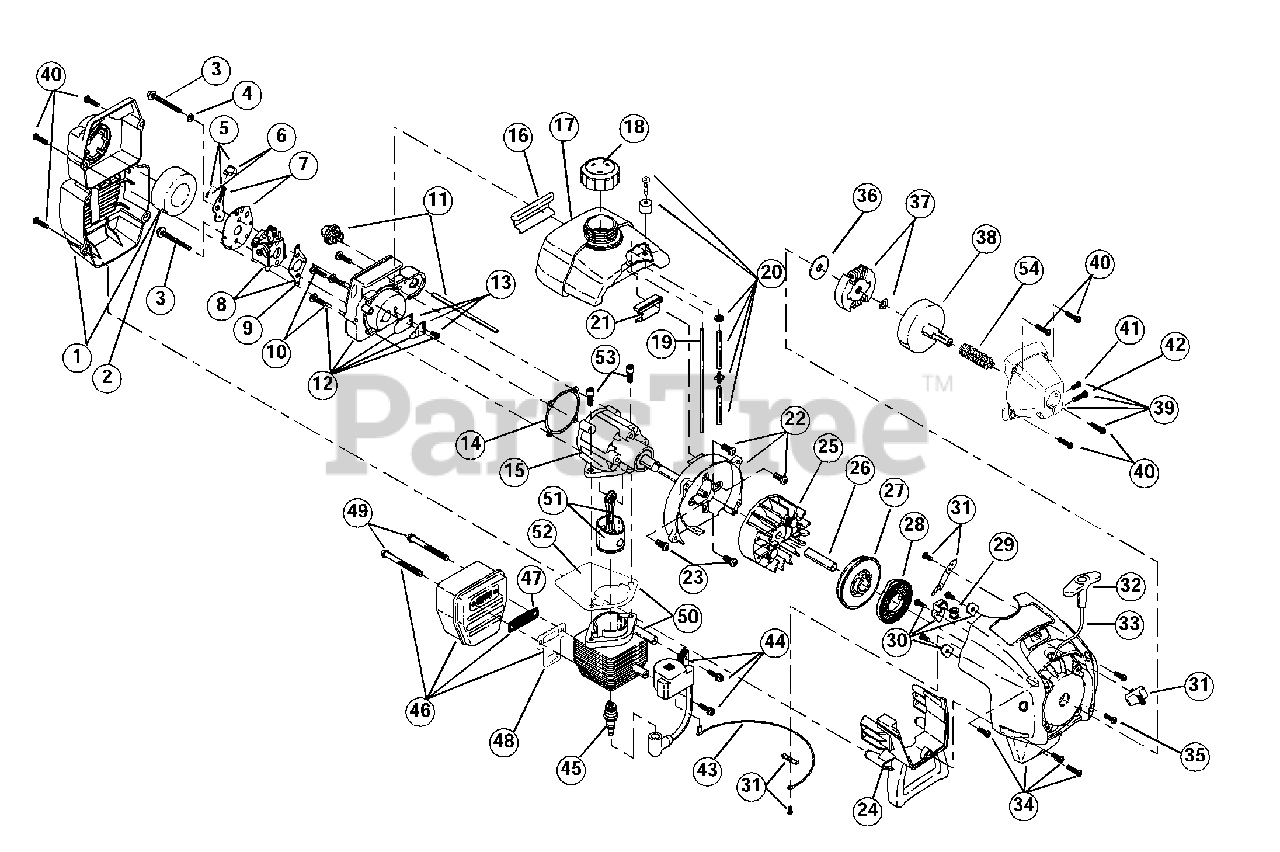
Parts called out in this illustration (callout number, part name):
1	Air Cleaner/Muffler Cover Assembly
2	Air Cleaner Filter
3	Carburetor Mounting Screw Assembly
4	Wavey Washer
5	Choke Lever Assembly
6	Choke Knob and Screw
7	Choke Lever and Plate
8	Carburetor Assembly
9	Carburetor Gasket
10	Carb Mount Screw
11	Primer and Hose Assembly
12	Carb Mount Assembly
13	Reed Assembly
14	Carburetor Mount Gasket
15	Crank Case Service Assembly
16	Rear Mounting Pad
17	Fuel Tank Assembly
18	Fuel Cap Assembly
19	Fuel Return Line
20	Fuel Line Assembly
21	Front Mounting Pad
22	Shroud Assembly
23	Shroud Screw
24	Shroud Extension and Stand
25	Flywheel Assembly
27	Recoil Pulley Assembly
28	Recoil Spring
29	Rope Guide
30	Pulley Retainer Assembly
31	Switch Assembly
32	Pull Handle
34	Starter Housing Assembly
35	Housing Screw
36	Clutch Washer
37	Clutch Rotor Assembly
38	Clutch Drum Assembly
39	Clutch Cover Assembly
40	Cover Screw
41	Anti-Rotation Screw
42	Clamping Screw
43	Wire Lead
44	Module Assembly
45	Spark Plug
46	Muffler Assembly
47	Spark Arrestor Screen
48	Exhaust Gasket
49	Muffler Mounting Bolt Assembly
50	Cylinder Assembly
51	Piston and Rod Assembly
52	Cylinder Gasket
53	Cylinder Bolt
